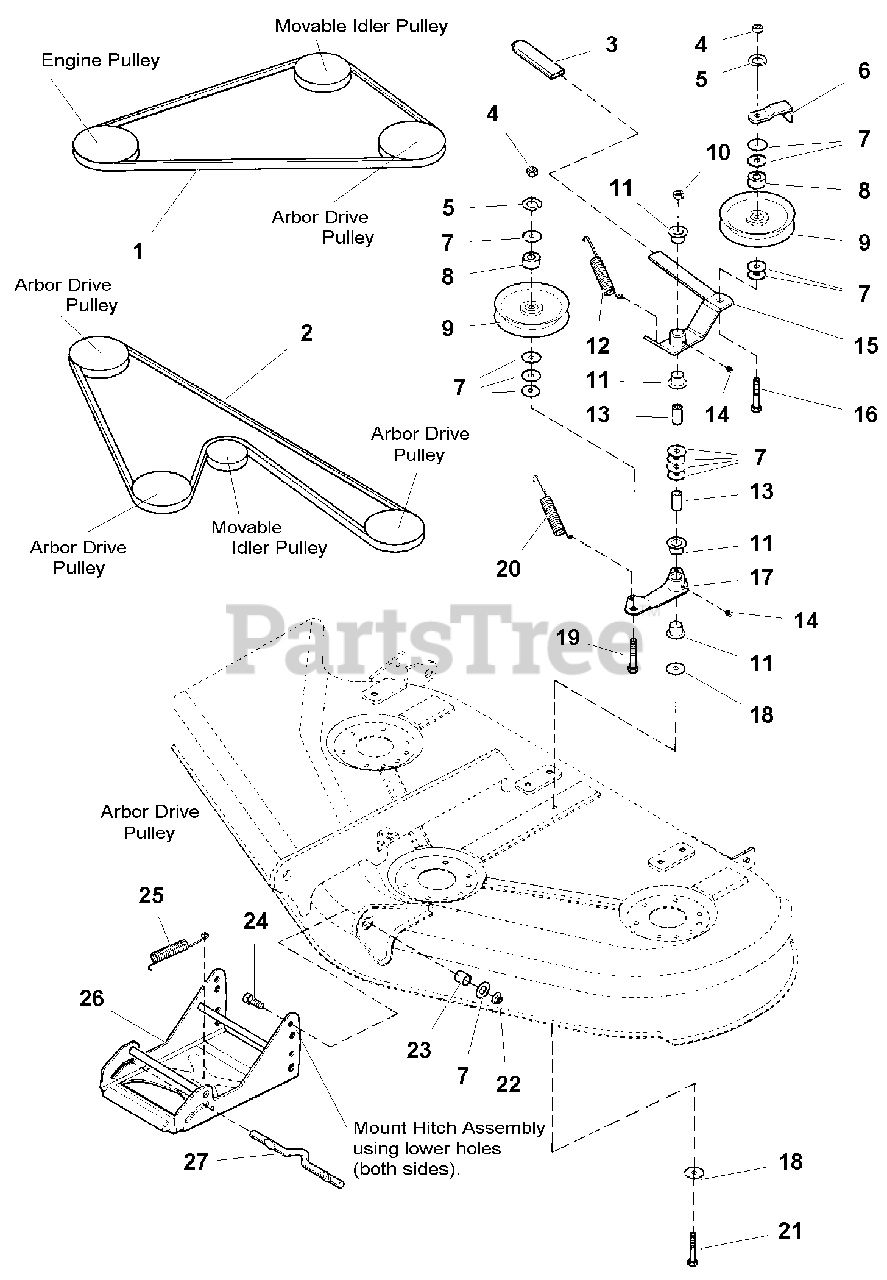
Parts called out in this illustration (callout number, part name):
1	V-BELT, Mower Drive (44" Decks)
1	V-BELT, Mower Drive (50" Decks)
2	V-BELT, Arbor Drive (50" Decks)
2	V-BELT, Arbor Drive (44" Decks)
3	GRIP, Lever
4	NUT, Hex, 3/8-16
5	WASHER, Lock, 3/8
6	BELT STOP, Idler
7	WASHER, 3/8
8	SPACER
9	PULLEY, Idler (Includes Ref. No. 8)
10	NUT, Hex Flange, 2-Way Lock, 3/8-16
11	BUSHING
12	SPRING
13	SPACER
14	GREASE FITTING
15	LEVER ASSEMBLY, Idler (Includes Ref. Nos. 11 & 14)
16	CARRIAGE BOLT, 3/8-16 x 2
17	LEVER ASSEMBLY, Idler Arm (Includes Ref. Nos. 11 & 14)
18	WASHER
19	CARRIAGE BOLT, 3/8-16 x 1-1/2
20	SPRING
21	CAPSCREW, Hex Head, 3/8-16 x 3-1/2
22	NUT, Hex Alum Insert Lock, 3/8-16
23	SPACER
24	CAPSCREW, Hex Head, 3/8-16 x 1-1/2
25	SPRING
26	HITCH ASSEMBLY
27	ROD, Latch
